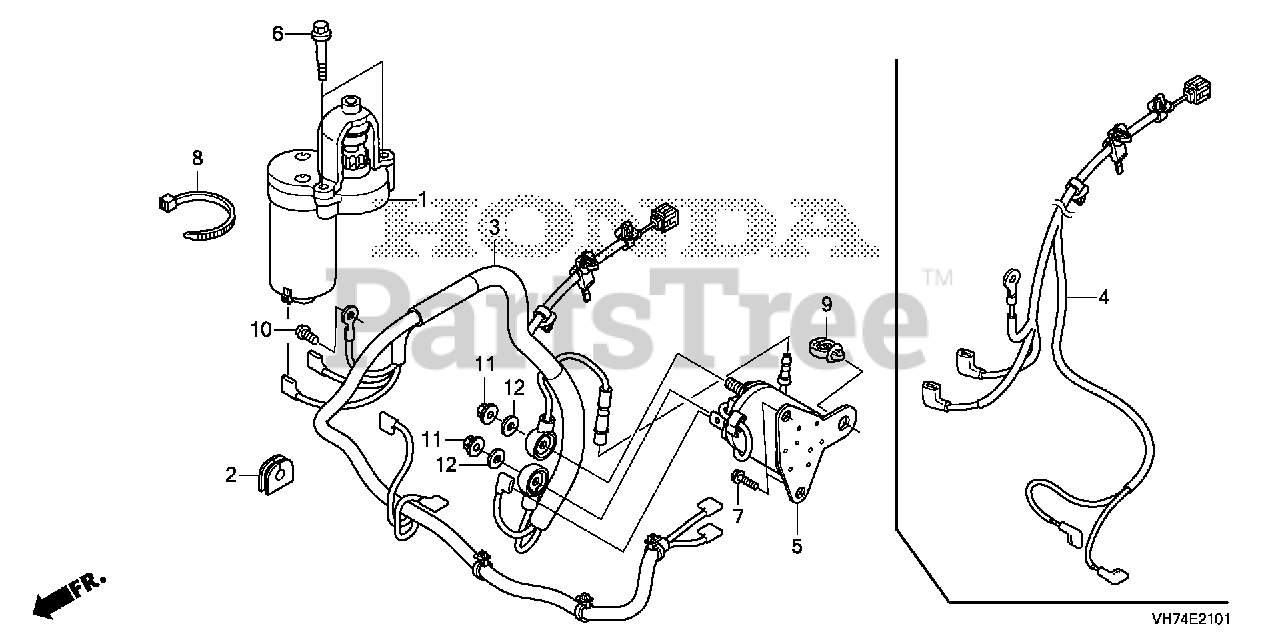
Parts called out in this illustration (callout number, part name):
1	STARTER MOTOR ASSY.
2	GROMMET, WIRE
4	WIRE HARNESS ASSY., ENGINE (SEL)(BBC)
6	BOLT, SPECIAL (6MM)
8	BAND, WIRE HARNESS
10	SCREW, PAN (5X8)
